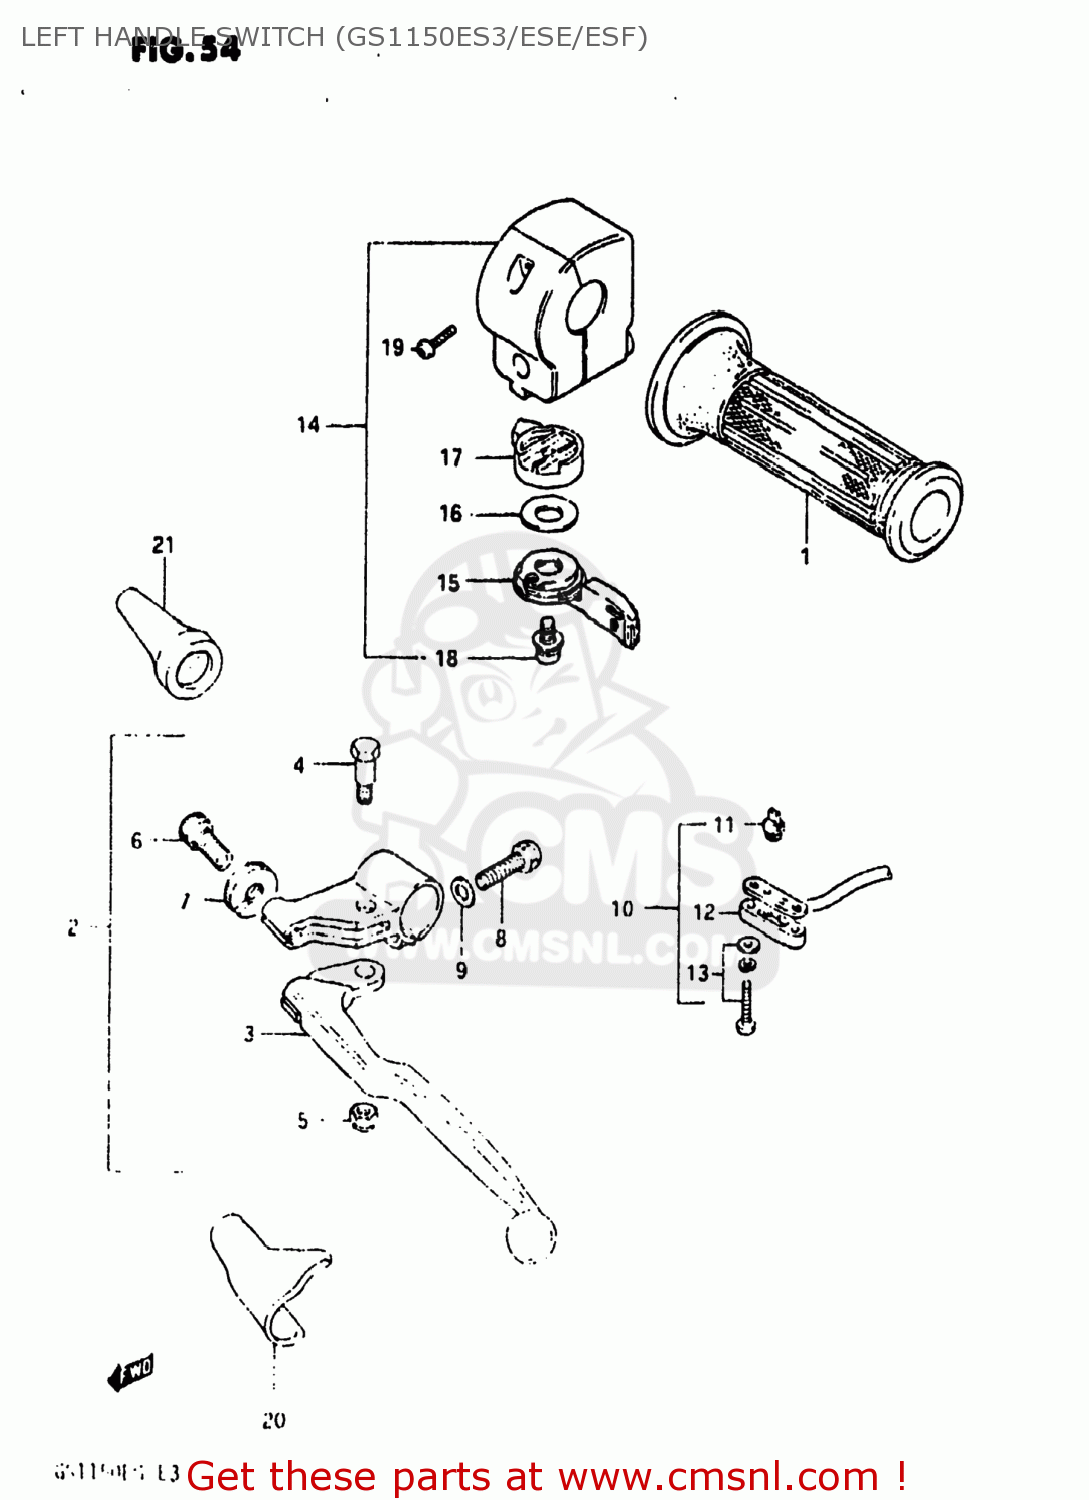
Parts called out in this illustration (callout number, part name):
1	GRIP,L
2	LEVER/SWITCH ASSEMBLY,CLUTCH
3	LEVER,CLUTCH
4	BOLT,LEVER PIVOT
5	NUT
6	ADJUSTER,CABLE
7	NUT,CABLE ADJUSTER LOCK
8	BOLT
9	WASHER
10	SWITCH ASSEMBLY,CLUTCH
11	CONTACT,SWITCH
12	COVER,FR BK TERMINAL BASE
13	SCREW
14	SWITCH ASSEMBLY,HANDLE,LEFT
15	LEVER,STARTER
16	WASHER,ADJUSTER
17	BODY,STARTER LEVER
18	SCREW,CHOKE LE
19	SCREW
20	COVER,CLUTCH LEVER
21	BOOT,CLUTCH CABLE
